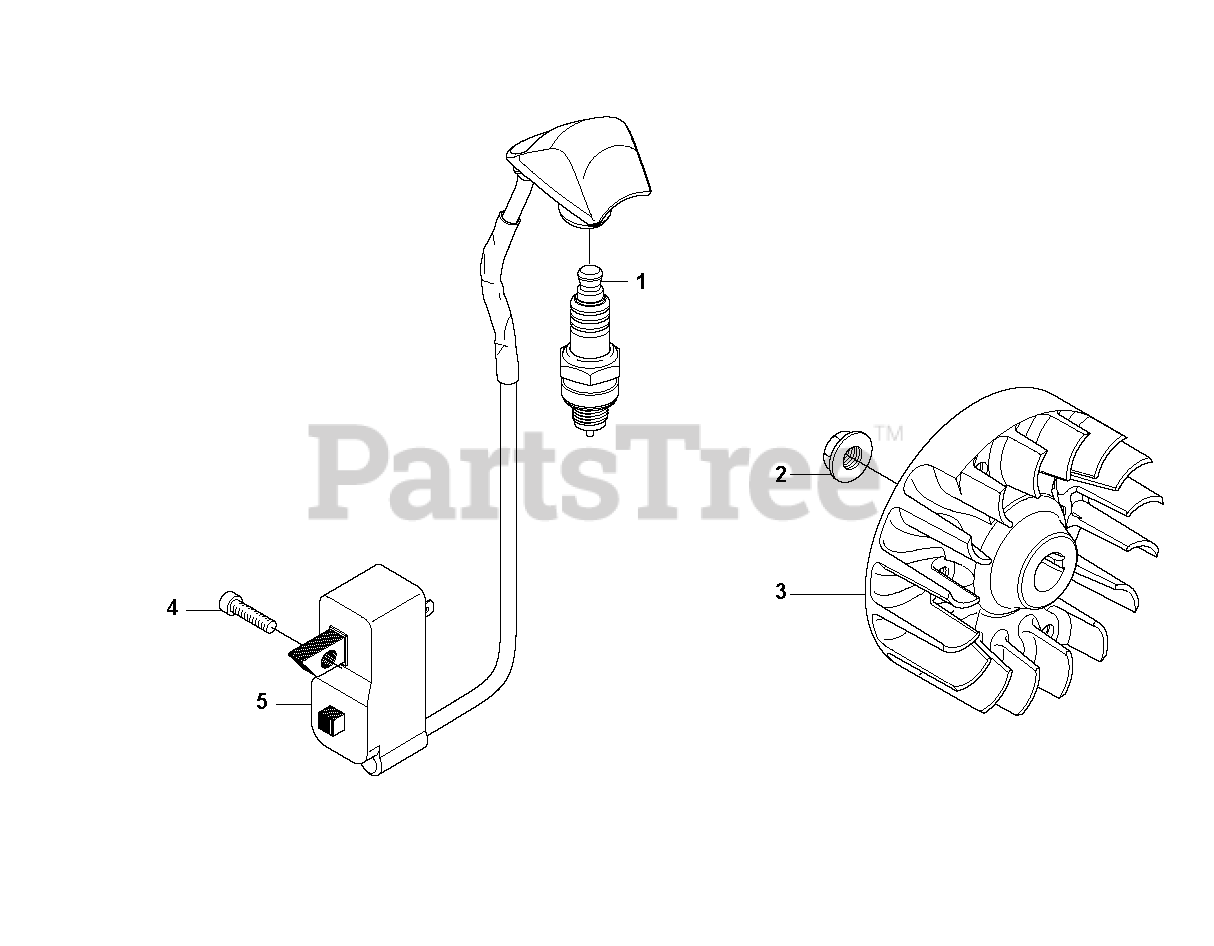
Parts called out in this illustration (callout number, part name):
1	SPARK PLUG RCJ6Y NLA
2	FLANGE NUT
3	FLYWHEEL
5	IGNITION MODULE OPS
